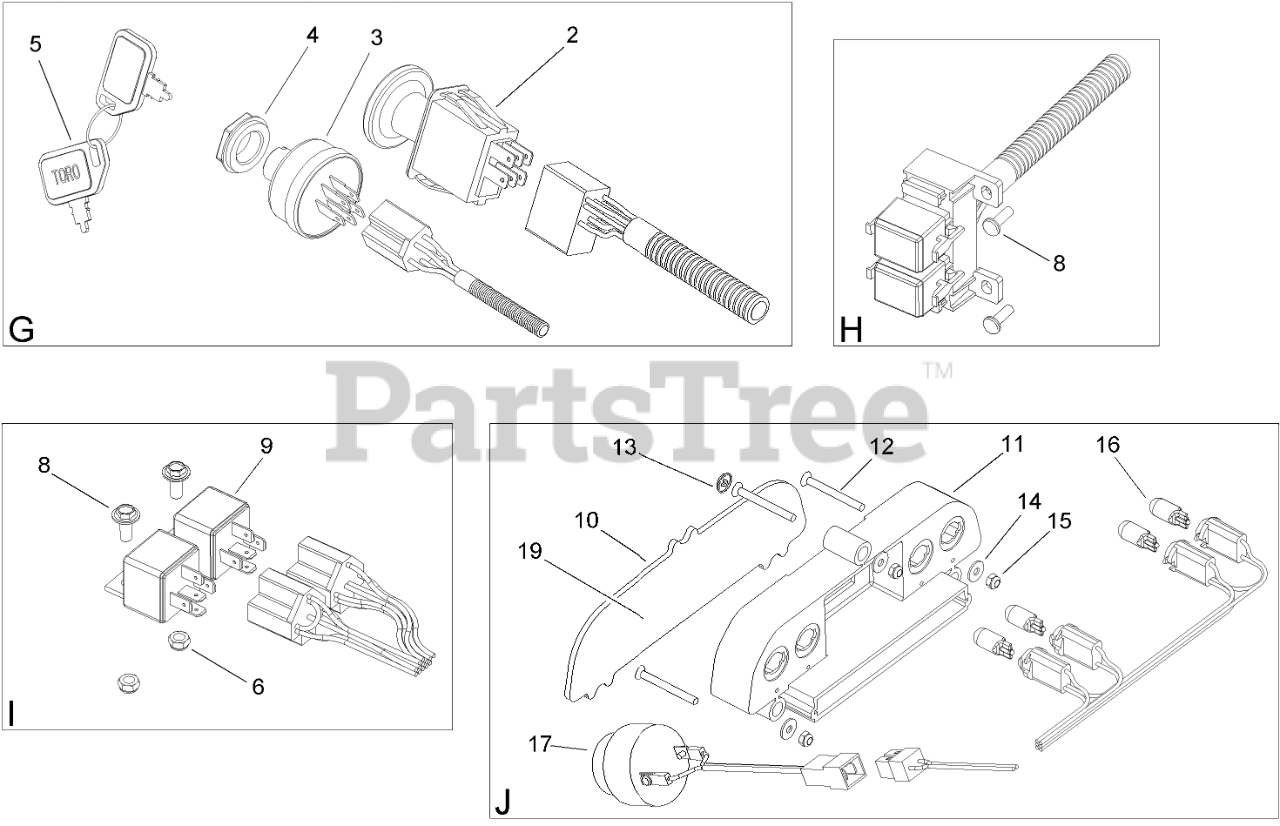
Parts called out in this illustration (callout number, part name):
2	SWITCH-PTO
3	SWITCH-IGNITION
4	NUT-HEX
5	KEY-IGNITION
6	NUT-LOCK
8	SCREW-HEX
10	LENS-DASH
11	HOUSING-LIGHT, INDICATOR
13	CAP-SCREW
14	WASHER
15	NUT-HEX
17	BUZZER
19	DECAL-DASH
